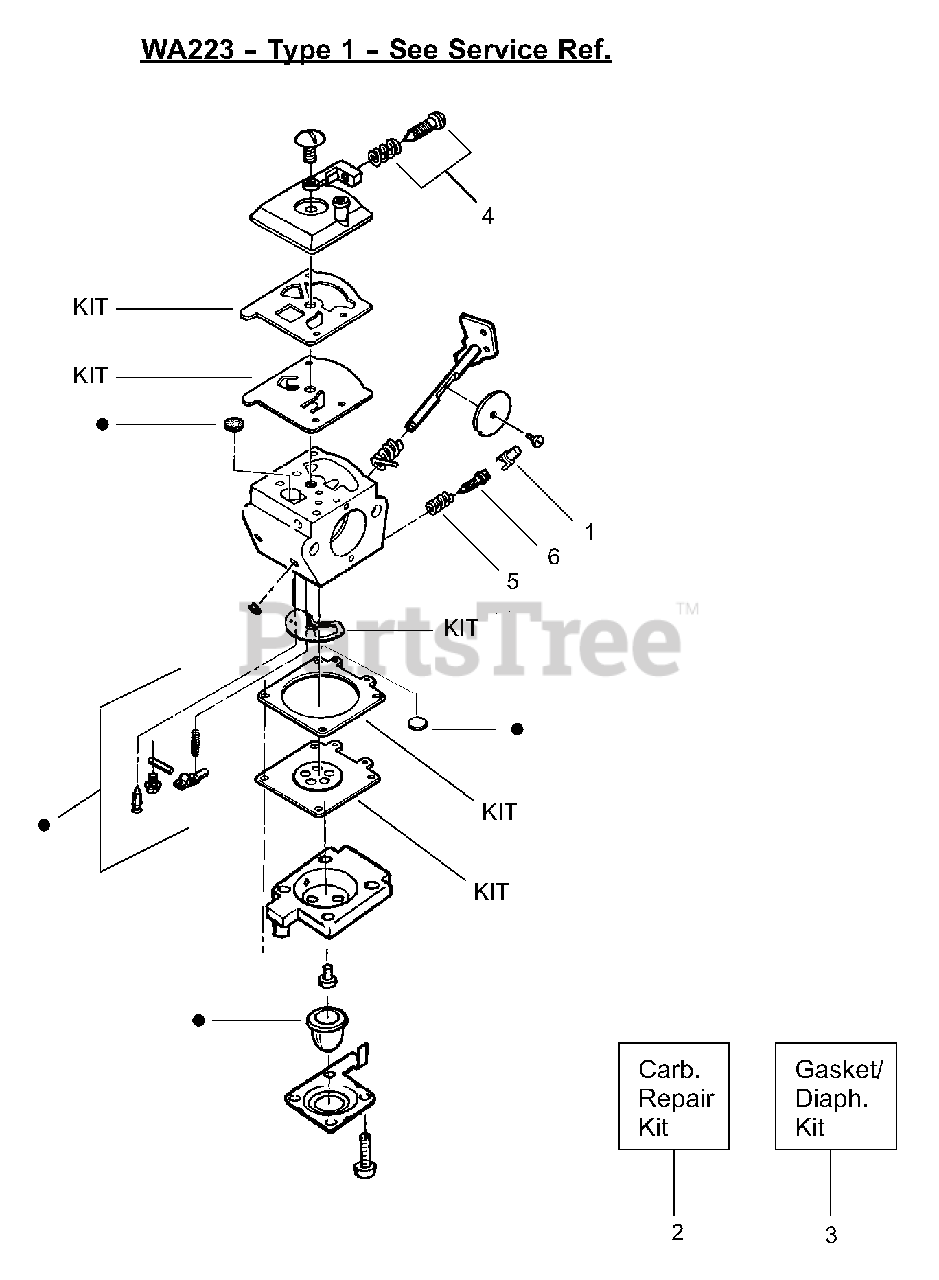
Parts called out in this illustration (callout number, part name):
1	Limiter Cap
2	Carburetor Repair Kit WA223
3	Gasket/Diaphragm Kit WA223
4	Idle Screw & Spring Kit
5	Low Speed Spring
6	Low Speed Needle
